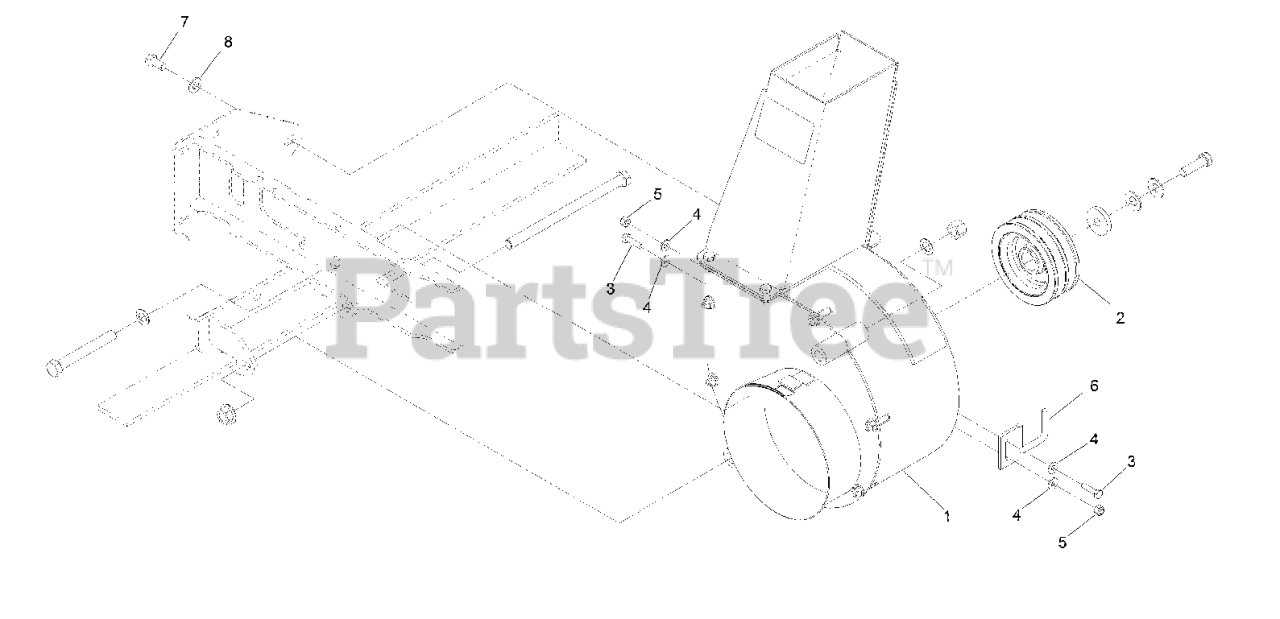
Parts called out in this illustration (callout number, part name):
1	Blower ASM
2	Sheave-Blower
3	Screw-HH
4	Washer-Flat
5	Nut-Lock, NI
7	Screw-HH
8	Washer-Flat
